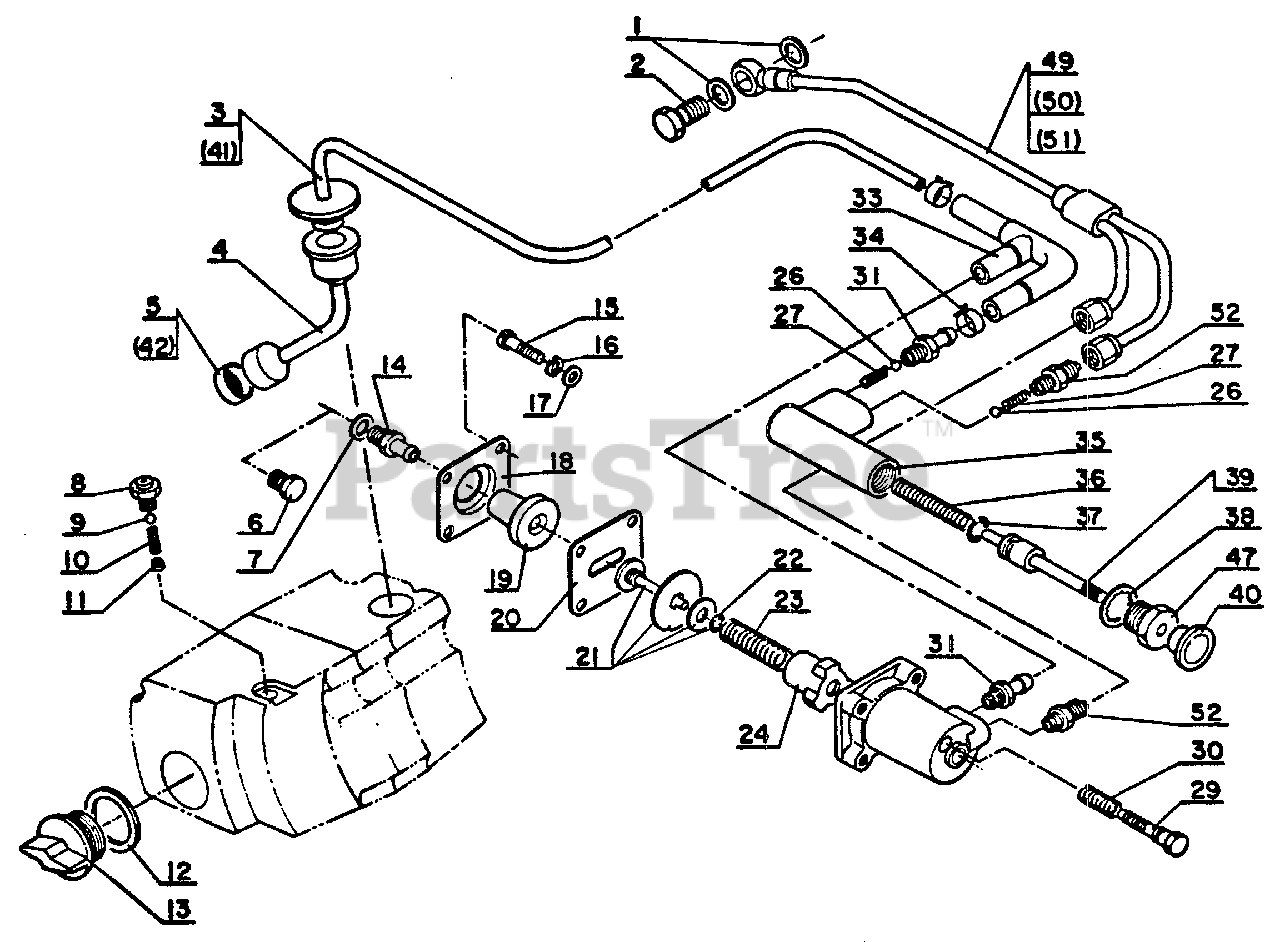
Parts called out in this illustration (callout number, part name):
1	GASKET
2	BOLT, HOLDING
3	PIPE, OIL
4	PIPE, OIL
5	FILTER, OIL
6	PLUG (ADAPTER)
8	NUT, AIR BREED
9	VALVE, BALL
10	SPRING, AIR BLEED
11	PLUG, AIR BREED
13	CAP, OIL TANK
15	SCREW 4×15
16	WASHER, SPRING 4 MM
17	WASHER, FLAT 5.5×10×0.8
18	RETAINER
19	CONNECTOR
21	PLUNGER ASSY
22	O-RING 3
23	SPRING, ADJUST
24	SPRING CASE
26	VALVE, BALL
27	SPRING, VALVE
29	SCREW, ADJUSTER
30	SPRING
31	CONNECTOR
33	PIPE, OIL
34	CLIP
35	BODY, OIL PUMP
36	SPRING, OIL PUMP
37	O-RING 6 MM
38	WASHER, LOCK
39	PUMP PISTON
49	PIPE, OIL
52	CONNECTOR
